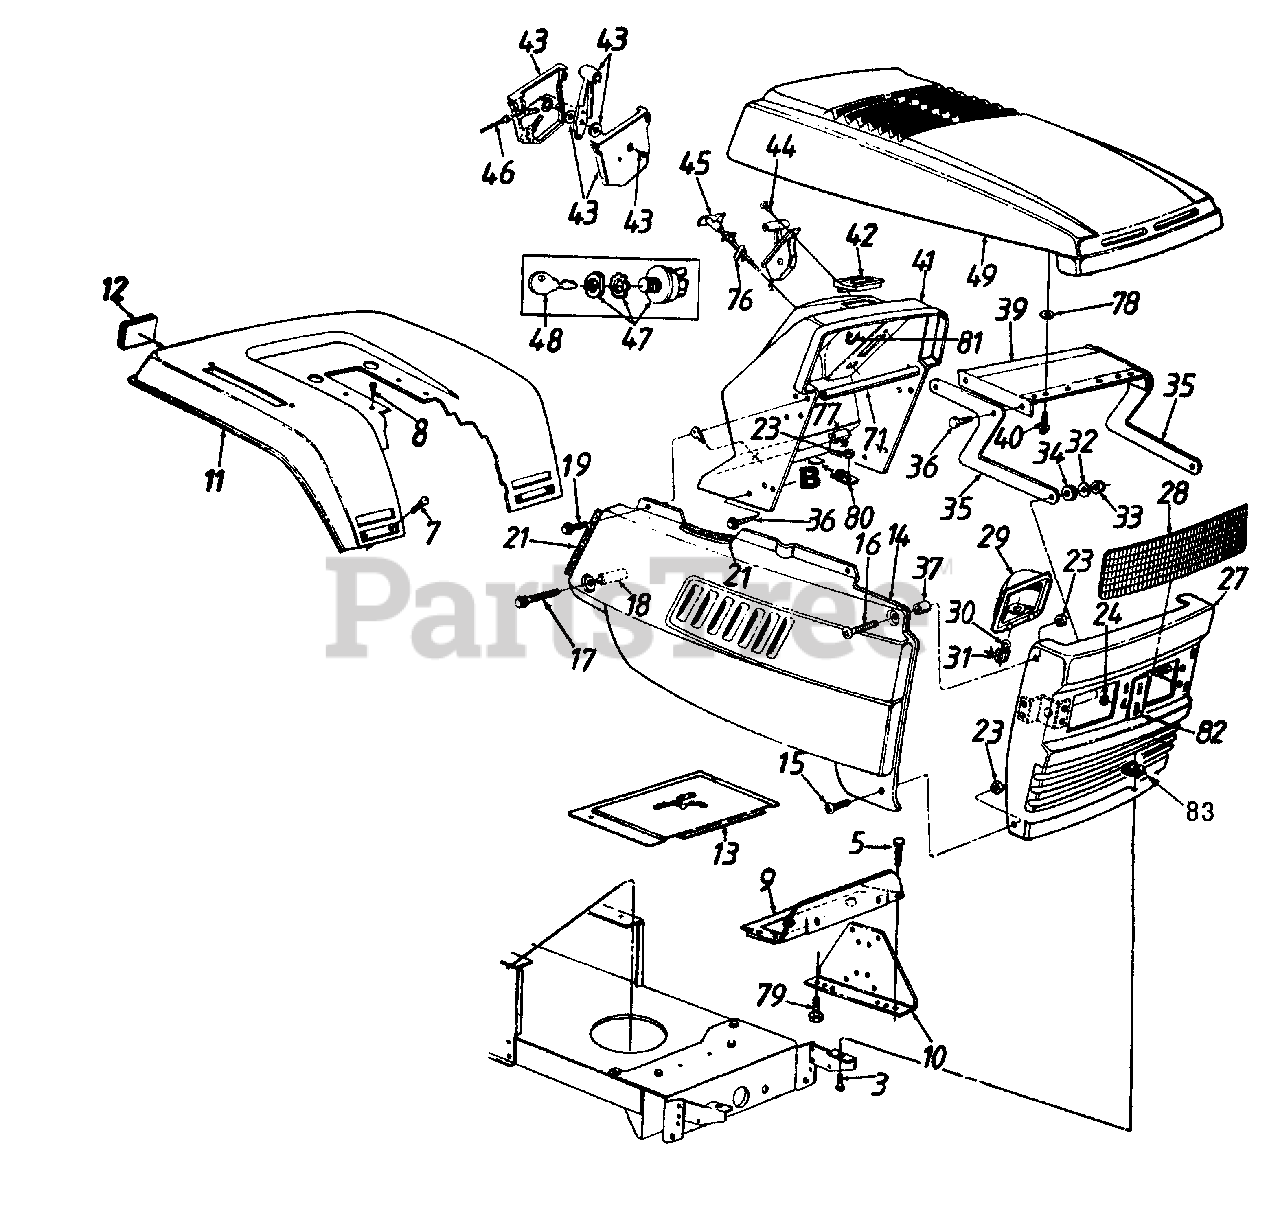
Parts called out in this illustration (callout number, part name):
3	Hex Bolt 5/16-18 x .75" Lg.
5	Hex Wash. Hd. Scr. 5/16" x .5" Lg.
7	Truss Mach. Scr. 1/4-20 x .5" Lg.
8	Hex Wash. Hd. Tap Scr.5/16 x .75" Lg.
16	Truss Mach. Scr. 1/4-20 x 1.0"
17	Hex Wash. TT-Tap Scr. 1/4-20 x
18	Spacer .26" I.D. x 1.32"
19	Hex Rolling Tap Scr. 1/4-20 x .75" Lg.
21	Trim Strip 18" Lg.
23	Hex Sems Nut 1/4-20 Thd.
24	Speed Nut 5/16" Thd.
29	Headlamp Housing
30	Headlamp
31	Twist Lock Lamp Socket
32	Bell-Wash. .345" I.D. x .88"
33	Hex L-Nut 5/16-18 Thd.
34	Rubber Washer
37	Spacer .262" I.D. x .31"
41	Dash
42	Ammeter
43	Throttle Control Box Ass'y.
44	Mach. Scr. #10 x .44" Lg.
45	Choke Control 23" Lg.
46	Throttle Control Wire 18.5" Lg.
47	Ignition Switch
48	Ignition Key
49	Hood-- Red
71	Grille Support Tube
76	Choke Retainer
77	Light Switch
78	Fl-Wash. .406" I.D. x .812" O.D.
79	Hex Bolt 1/4-20 x .88" Lg.
80	Dash Fastening Tab
81	Cable Tie
82	Chrome Label
83	U-Nut 5/16-18 Thd.
